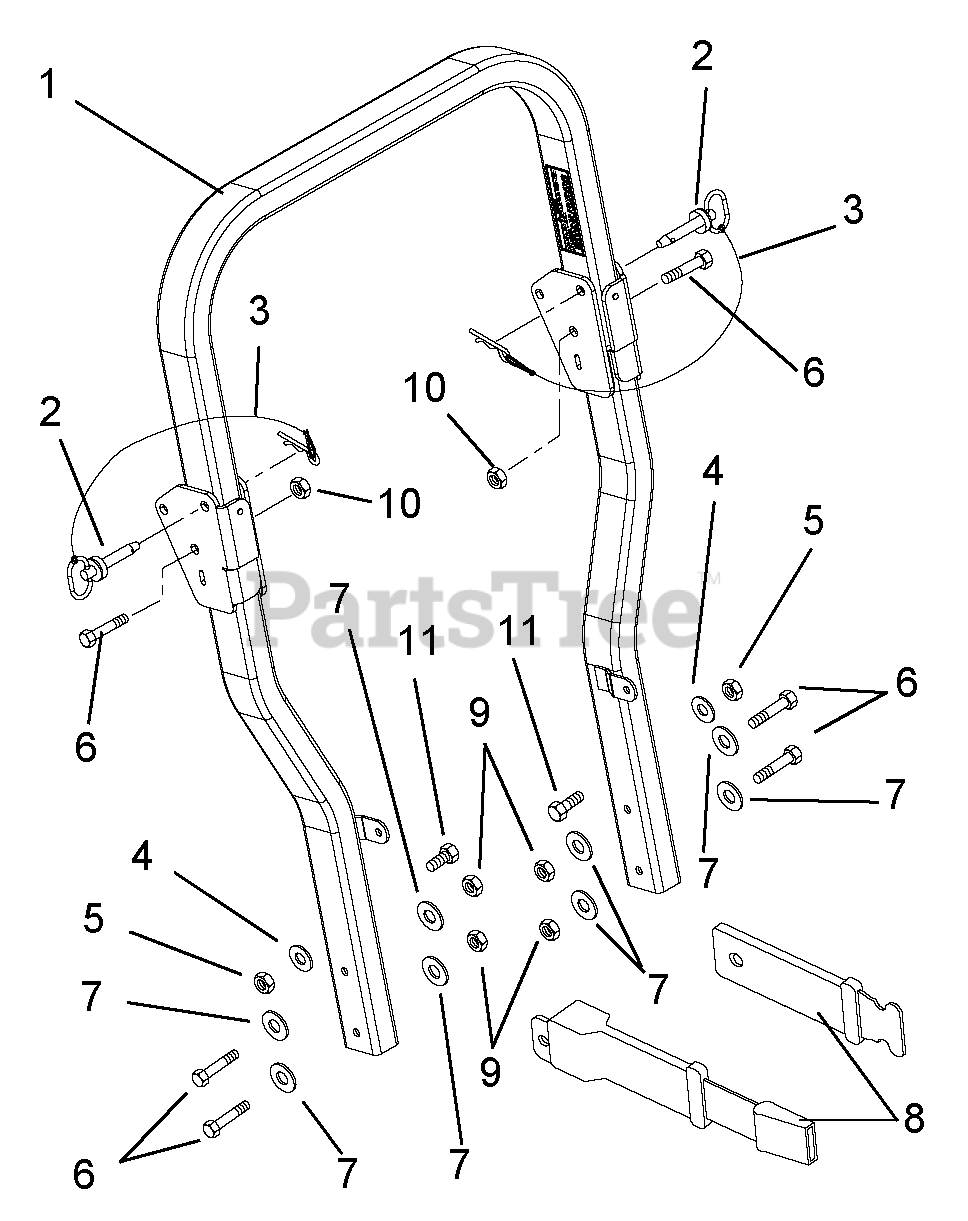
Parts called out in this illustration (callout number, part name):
1	Rollover Bar
2	Hitch Pin with Hairpin
4	Flat Steel Washer, 1/2" x 1-1/4" x 5/64"
5	Lock Nut, 7/16"-14
6	Hex Bolt, 1/2"-13 x 3-1/4" Grade 5
7	Flat Steel Washer, 9/16" x 1-3/8" x 7/64"
8	Retractable Seat Belt
9	Lock Nut, 1/2"-13
10	Center Lock Nut, 1/2"-13
11	Hex Bolt, 7/16"-14 x 1" Grade 5
